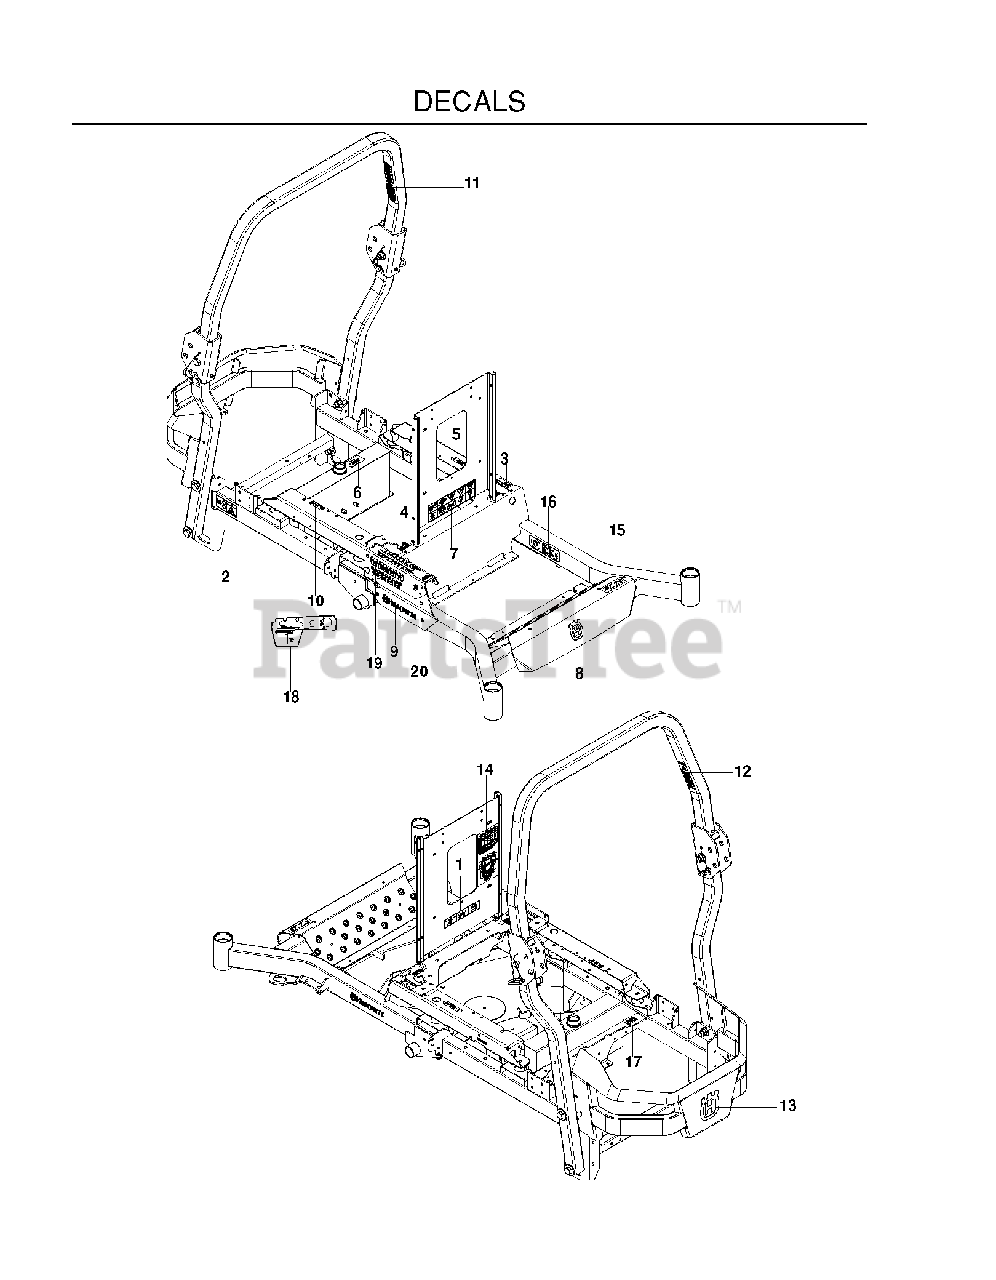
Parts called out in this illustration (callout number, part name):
1	EURO DECAL-BATTERY WARNIN6
2	DECAL, BELT DRIVE
3	DECAL, MOTION CONTROL
4	DECAL, F.S.T.
5	DECAL, PARK BRAKE
6	DECAL, OIL TANK
7	DECAL, WARNING
8	DECAL.AUGER.HUSQ.CROWN.SNOW
9	RP.DECAL.BADGE.170MM.TEXTLOGO
10	DECAL, FUSE
11	DECAL, ROPS
12	DECAL, ROPS, WARNING
13	DECAL, CROWN H, 110MM
14	DECAL, SERVICE
15	DECAL, PZ29
17	DECAL, FUEL
18	DECAL, CONTROL, GAS
19	DECAL, HEIGHT CE
20	DECAL, HEIGHT CE
